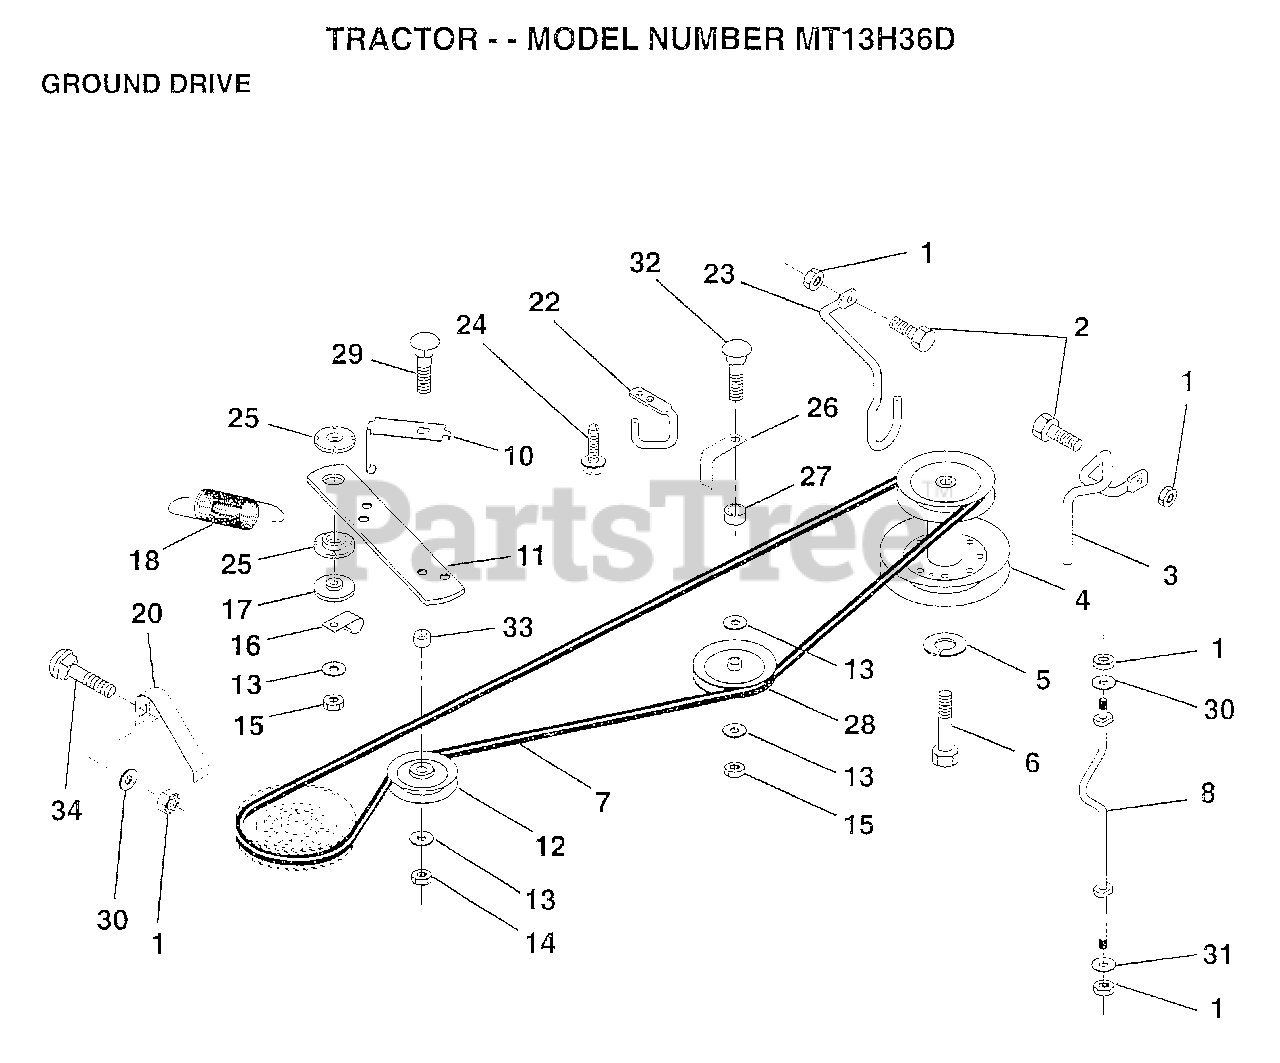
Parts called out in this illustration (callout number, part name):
1	NUT
2	BOLT
3	KEEPER.BELT.FRT.
4	PULLEY.ENGINE.LR
5	LOCKWASHER
6	HEX BOLT
7	BELT-V.DRV.77.75
8	KEEPER.BELT.HYDRO
10	KEEPER.BELT.GRD.
11	ARM-IDLER.DR.GRND
12	PULLEY.IDLER.FLAT
13	WASHER
14	LOCKNUT
16	"CLIP,INSULATOR"
17	SPACER
20	KEEPER.BELT.LH
22	"KEEPER,FRA DR BEL"
23	KEEPER MOWER LH
24	SCREW
25	BUSHING.NYLON
26	KEEPER.BELT.IDLER
27	SPACER.625X.843
28	PULLEY.IDLER.V.GR
29	BOLT RDHD 3/8-16
30	WASHER
31	WASHER M
32	BOLT
34	BOLT
